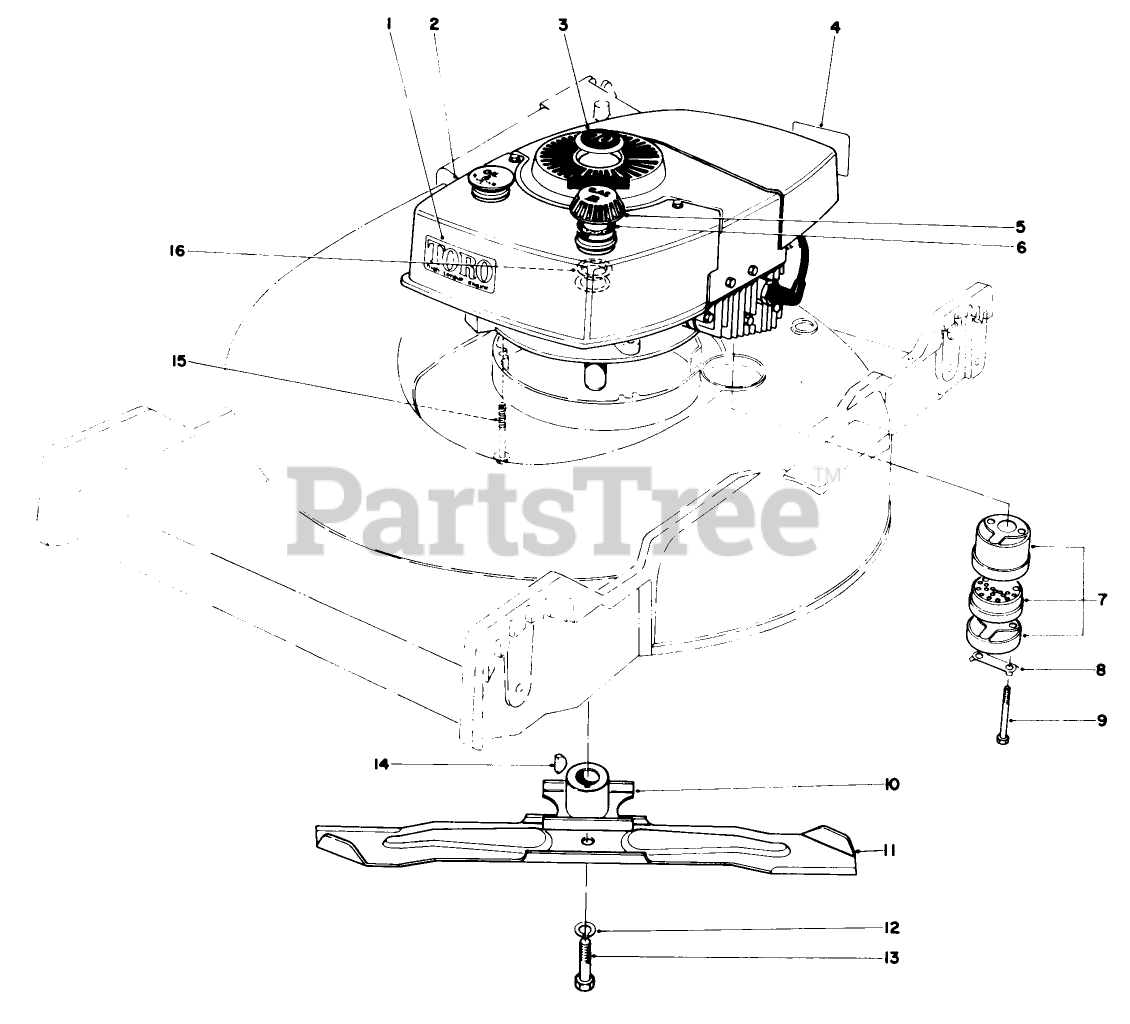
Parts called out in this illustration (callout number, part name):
1	High Torque
2	Engine
3	PLUG BUTTON
4	Decal Maintenance
5	Gas Cap (Incl. Ref. #6 & 16)
6	GASKET
7	Muffler Assembly (Incl. Ref. #8 & 9)
8	CLIP - LOCKING
9	SCREW-HH
10	BLADE RETAINER WA(BLACK)
11	Blade
12	WASHER-LOCK
13	BLADE SCREW
14	KEY-WOODRUFF
15	3/8-16 X 2-3/4 CAPSCR
16	GAS CAP BAFFLE
